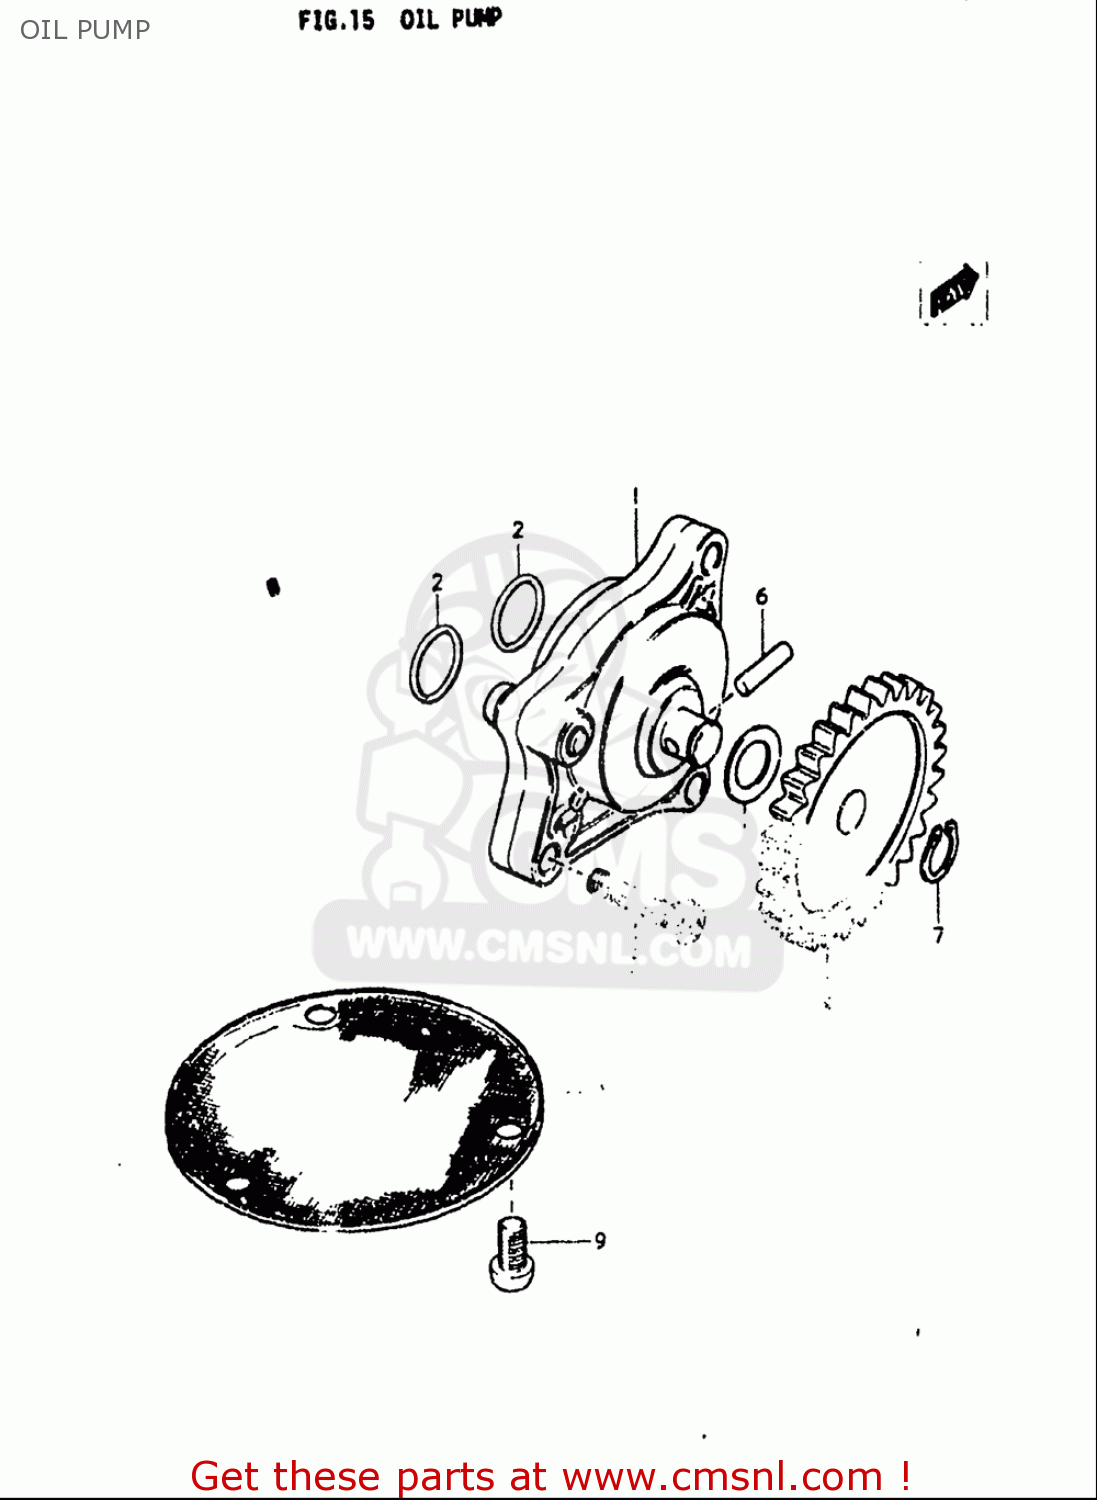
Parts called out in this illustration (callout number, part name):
1	PUMP ASSEMBLY,ENGINE OIL
2	O RING(D:1.9,ID:13)
3	SCREW
4	GEAR,ENG OIL PUMP DRIVEN
5	SHIM
6	PIN(4X15.8)
7	CIRCLIP
8	STRAINER,ENGINE OIL
9	SCREW
